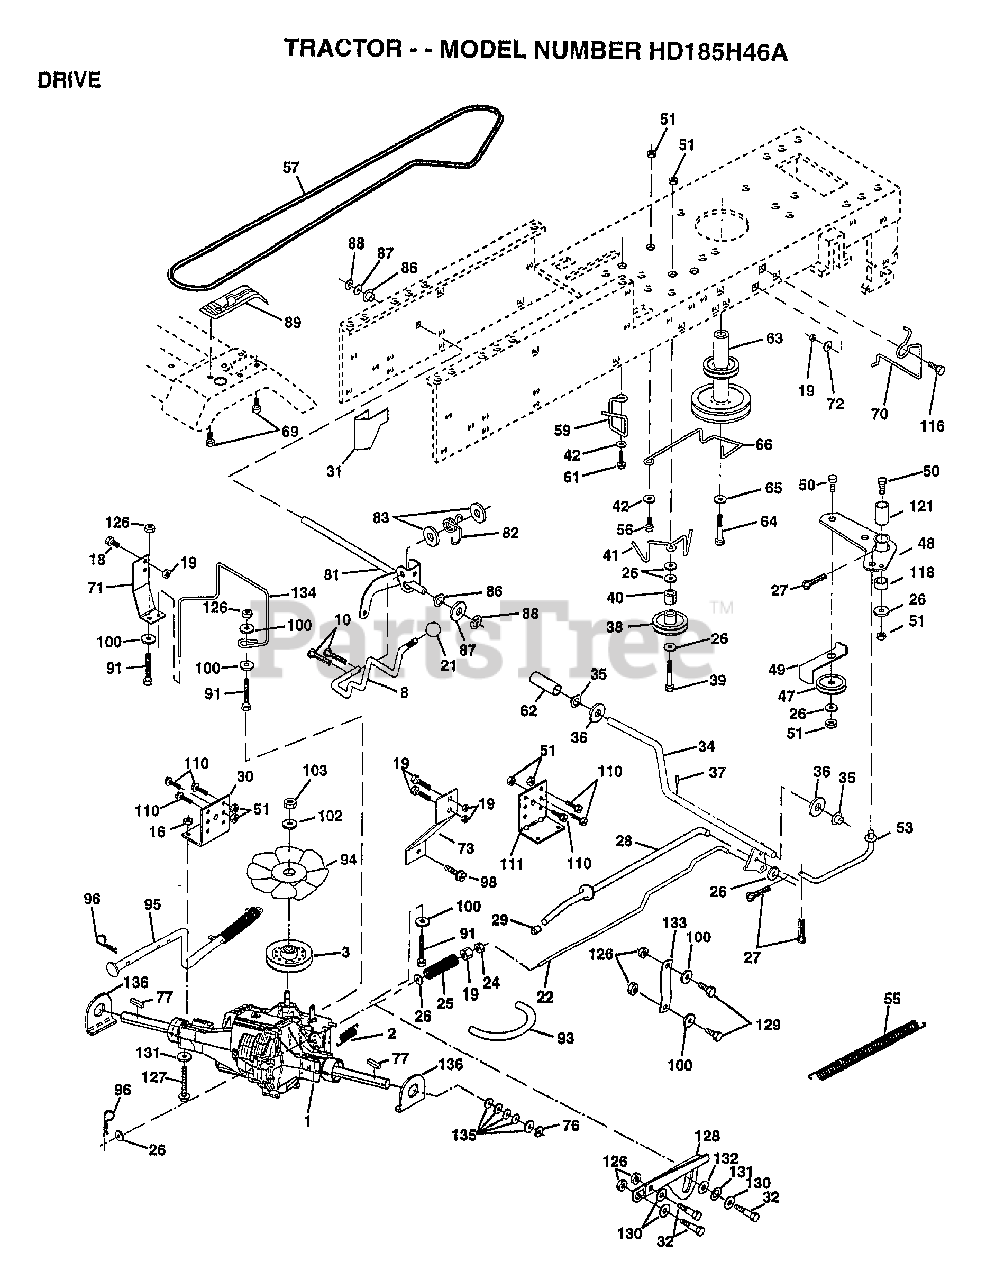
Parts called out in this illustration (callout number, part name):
2	SPRING RET BRAKE
3	PULLEY.TRANSAXLE
8	ROD SHIFT FEND YT
10	PIN COTTER 1/8
15	BOLT.HX.FLG.5/16
16	NUT
18	BOLT
19	NUT
21	KNOB T (1/2-HOLE)
22	BRAKE.ROD.HYDRO.
24	NUT
25	SPRING ROD LT
26	WASHER
27	COTTER PIN
28	ROD.BRAKE.PARK.LT
29	PLUNGER CAP T
30	BRKT TRANS LH
31	KEEPER BELT LH
32	BOLT
34	SHAFT ASM-PEDAL F
35	NYLON BEARING
36	WASHER LT
38	PULLEY.IDLER.FLAT
39	BOLT
40	SPACER T
42	WASHER
48	ARM IDLER
49	RETAIN BELT
53	"LINK, CLUTCH T"
55	"SPRING, RETURN LT"
59	KEEPER BELT CNTSP
61	SCREW
62	PEDAL COVER T
63	PULLEY.ENGINE
64	BOLT
65	LOCKWASHER
66	KEEPER-BELT
69	SCREW HEXWSH H-L
70	"GUIDE.BELT,RH ENG"
71	STRAP.TORQUE.LH.HYDRO
72	WASHER
73	STRAP.TORQUE.RH.HYDRO
76	E RING HYT
77	SQ KEY STD
81	SHAFT ASM. CROSS HYDRO 20" TIRES
82	"SPRING,TORSION"
83	WASHER
84	ROD.TIE.BALL.4.75
86	BUSHING
87	WASHER D
88	KLIP RING
93	"LINE FUEL HYD 4"""
94	"FAN 7"" HYDRO"
95	CONTROL.ASM.BYPAS
96	RETAINER M
97	BOLT KEEPER RH
100	WASHER M
102	WASHER BELLEVILLE
111	BRKT TRANS RH
116	BOLT RDHD 3/8-16
118	SPACER-BELLCRANK
121	NYLINER-CLUTCHING
122	"PLATE-BYPASS,PVST"
124	SPRING RETURN
127	BOLT.HEX.FLGHD.
128	BRKT NEUTRAL ADJ
129	BOLT.SHLD.5/16-18
130	"WSHER,SHIM"
131	LOCKWASHER
134	"KEEPER BELT,RH"
135	WASHER 1-1/32 X 1/5/8 X16 GA.
136	WASHER AXLE HYDRO
